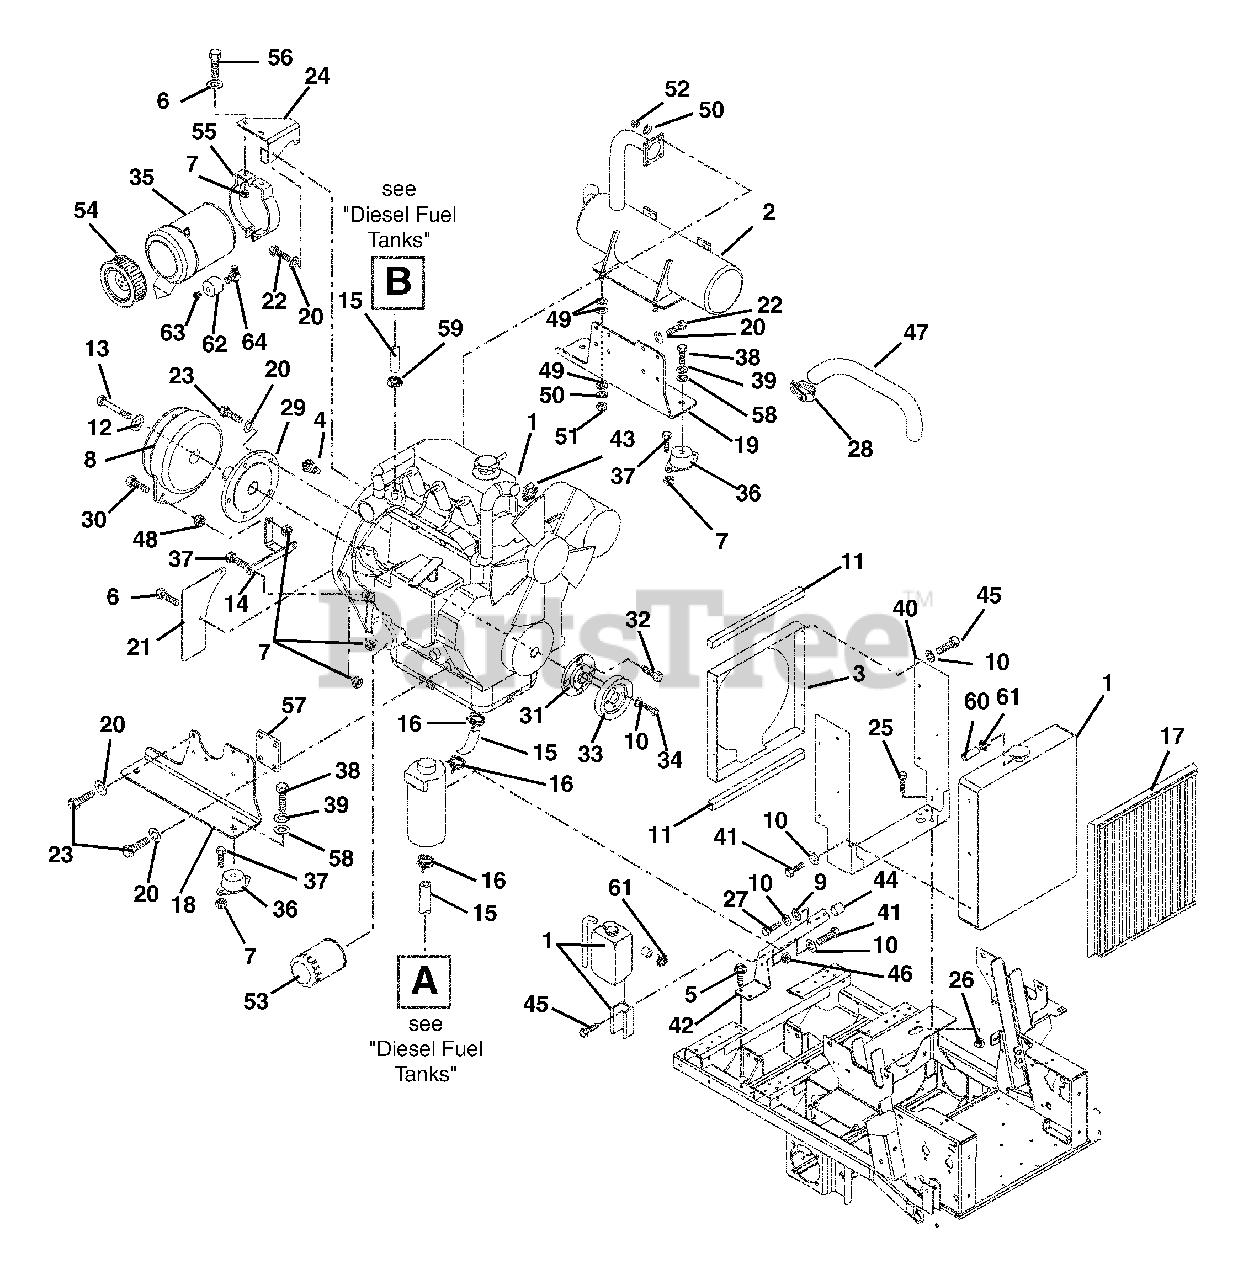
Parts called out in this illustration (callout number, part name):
1	Engine, 31HP Diesel (Daihatsu)
3	Weldment, Radiator Shroud
4	Sender, Temperature
5	Screw-Tapping .38-16 x .75 Hex Washer Head
6	Bolt-Hex .31-18 x .75 Grade 5
7	Nut-Locking-Nylon .31-18
8	Electric Clutch
9	Washer-Flat-Steel .281 x .62 x .065
10	Washer-Locking .25 x .062 Regular
11	Seal, Trim-LOK Bulk .06 Bubble
12	Washer-Locking .44 x .109
13	Bolt-Hex .44-20 x 2.50 Grade 5
14	Stabilizer, Clutch
15	Gas Line-Bulk .31" ID
16	Hose-Clamp
17	Screen, Radiator
18	Mount, Engine Right Hand
19	Mount, Engine Left Hand
20	Washer-Lock .31 x .078 Regular
21	Guard, Flywheel
22	Bolt-Hex M8-1.25 x 20
23	Bolt-Hex M8 x 1.25 x 25 Grade 8
24	Bracket, Air Cleaner
25	Bolt-Hex .38-16 x 1.00 Grade 5
26	Nut-Locking-Nylon .38-16
27	Bolt, Hex M6-1.00 x 45
28	Clamp, 2.25 Dia. Hose
29	Weldment, Stub Shaft
30	Bolt-Hex .31-18 x 1.50 Grade 5
31	Adapter, Sheave
32	Bolt, M8-1.25 x 25
33	Sheave, Poly-V 1.0 x 3.25
34	Bolt-Hex .25-20 x .50 Grade 5
35	Assembly, Air Cleaner
36	Mount, Engine
37	Bolt-Hex .31-18 x 1.00 Grade 5
38	Bolt-Hex .50-20 x 1.00 Grade 5
39	Washer-Locking .50 x .125 Regular
40	Bracket, Radiator Mounting
41	Bolt-Hex M6-1 x 16
42	Bracket, Overflow Mounting
43	Clamp-Hose 1.50 x .81 x 1.42
44	Spacer .328 x .76 x 1.01
45	Bolt-Hex .25-20 x .75 Grade 5
46	Nut-Locking-Nylon .250-20
47	Hose, Air Cleaner
48	Nut-Hex .31-18
49	Washer-Flat-Steel .38 x .875 x .083
50	Washer-Locking .31 x .078 Regular
51	Nut-Hex .31-18
52	Nut-Hex M8-1.25
53	Oil Filter
54	Element, Air Cleaner
55	Bracket, Air Cleaner
56	Washer-Flat-Steel .38 x .875 x .083
57	Spacer, Engine Mounting
58	Washer-Flat-Steel .531 x 1.06 x .095
59	Hose Clamp
60	Gas Line-Bulk .25 I.D.
61	Clamp-Hose Wire .49/.51 x .116
62	Filter Minder
63	Nipple, .125
64	Elbow,Adaptor 90 Degree, Brass, .125 x .125
